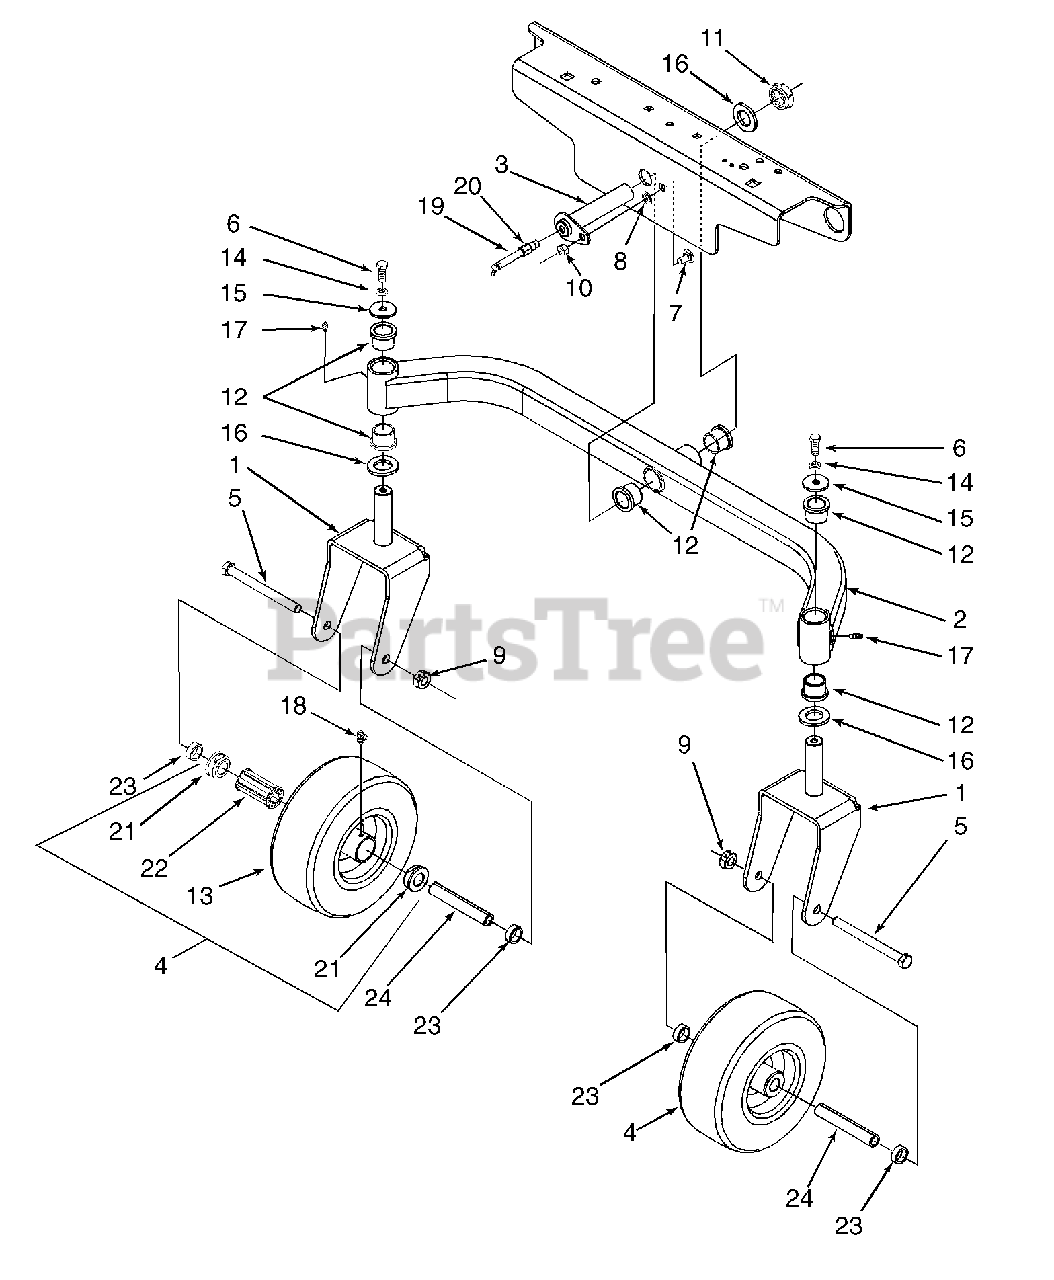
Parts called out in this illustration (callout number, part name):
4	Wheel Ass'y, 9.0 x 3.70-4
5	Screw, Hex Cap, 1/2-20 x 5.5
6	Screw, Hex Cap, 3/8-16 x 1.0 GR5
7	Bolt, Carriage, 3/8-16 x .75
8	Push Nut, Retainer, 3/8 ID
9	Nut, Hex Center Lock, 1/2-20
10	Nut, Hex Flange Lock, 3/8-16
11	Nut, Hex Lock, 1.0-14
12	Bearing, Flange, 1.0 ID
13	Tire, Urethane, Only
14	Washer, Lock 3/8
15	Washer, Flat, .39 x 1.5 x .134
16	Washer, Special Flat
17	Fitting, Grease
18	Fitting, Grease, 90° Tap 1/4-28
19	Fitting, Grease, 65° w/Extension
20	Adapter, 1/8 NPTF x 1/8 NPTF
21	Bearing, Flange
22	Bearing, Roller
23	Spacer, .79 ID x .347 Lg
24	Spacer, Wheel
